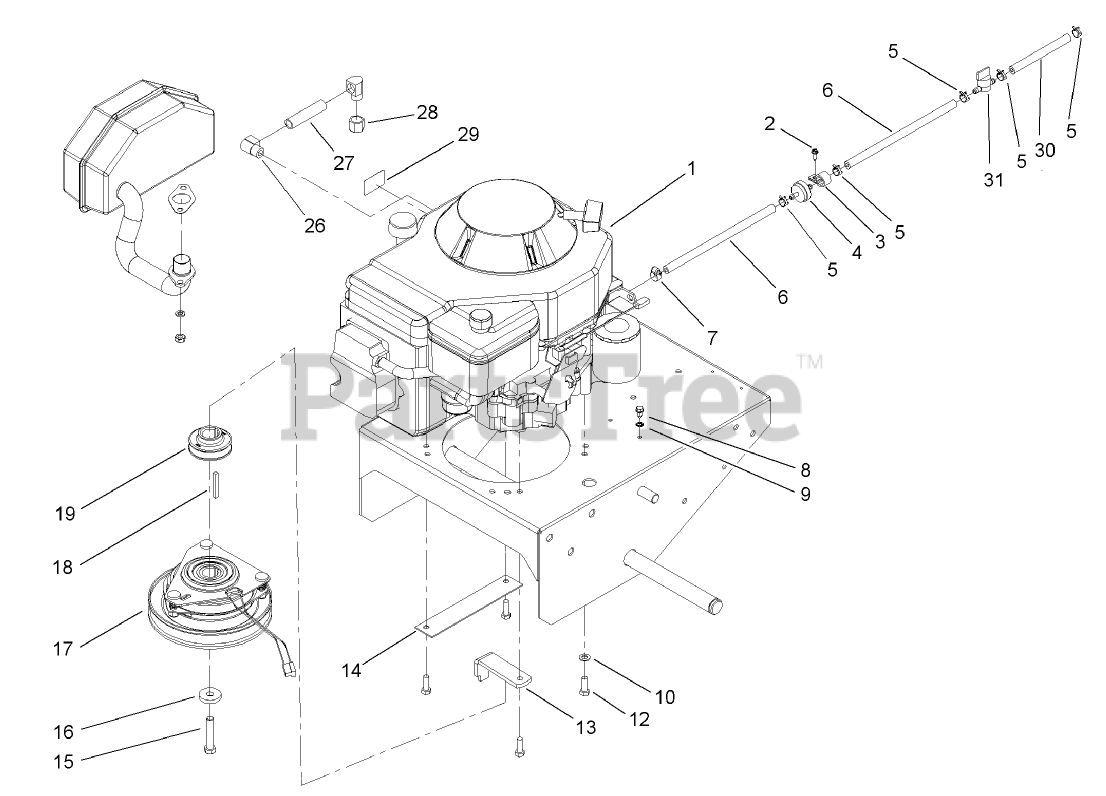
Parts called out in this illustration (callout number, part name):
2	SCREW-SHWH
3	CLAMP-CABLE
4	FILTER-FUEL
5	CLAMP-HOSE
6	HOSE-FUEL
7	CLAMP-WORM
8	SCREW
9	WASHER-LOCK/EXT
10	WASHER-PLAIN
12	SCREW-HH
13	RETAINER-CLUTCH
14	GUARD-PULLEY
15	SCREW-HH
16	WASHER
17	CLUTCH / BRAKE ASM
18	KEY-SQUARE
19	PULLEY-DRIVE
26	ELBOW-STREET, 90 DEG
27	NIPPLE-PIPE
28	CAP-PIPE
29	DECAL-WARNING
30	HOSE-FUEL
31	VALVE-FUEL
